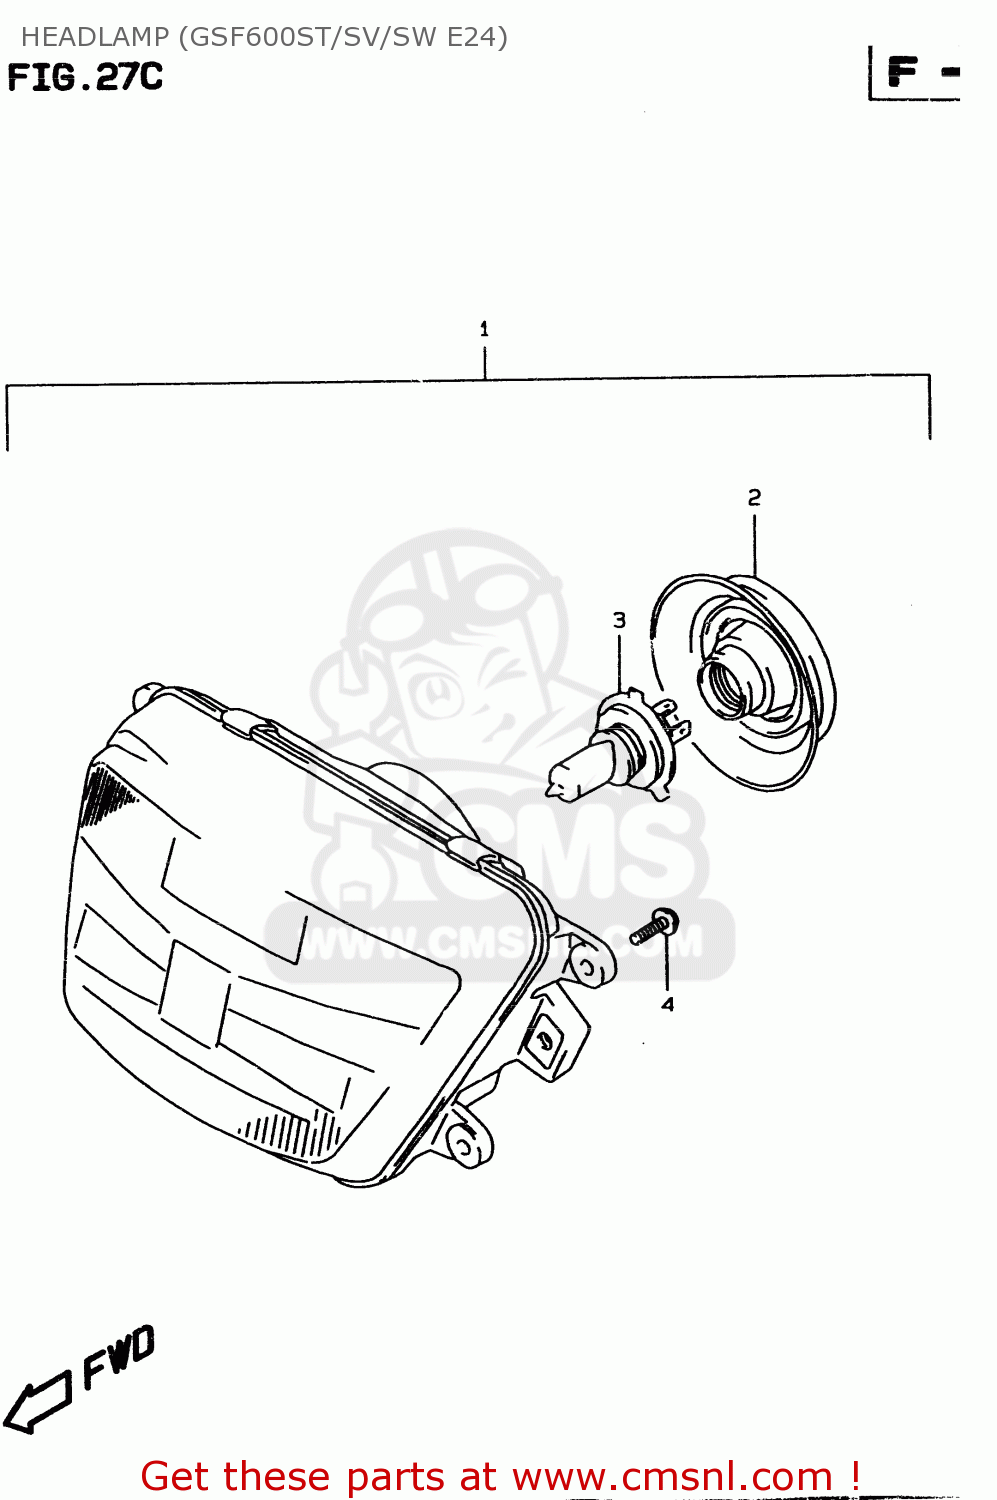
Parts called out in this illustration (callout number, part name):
1	HEADLAMP ASSY
2	COVER,SOCKET
3	BULB(12V60/55W,H4)
4	SCREW
